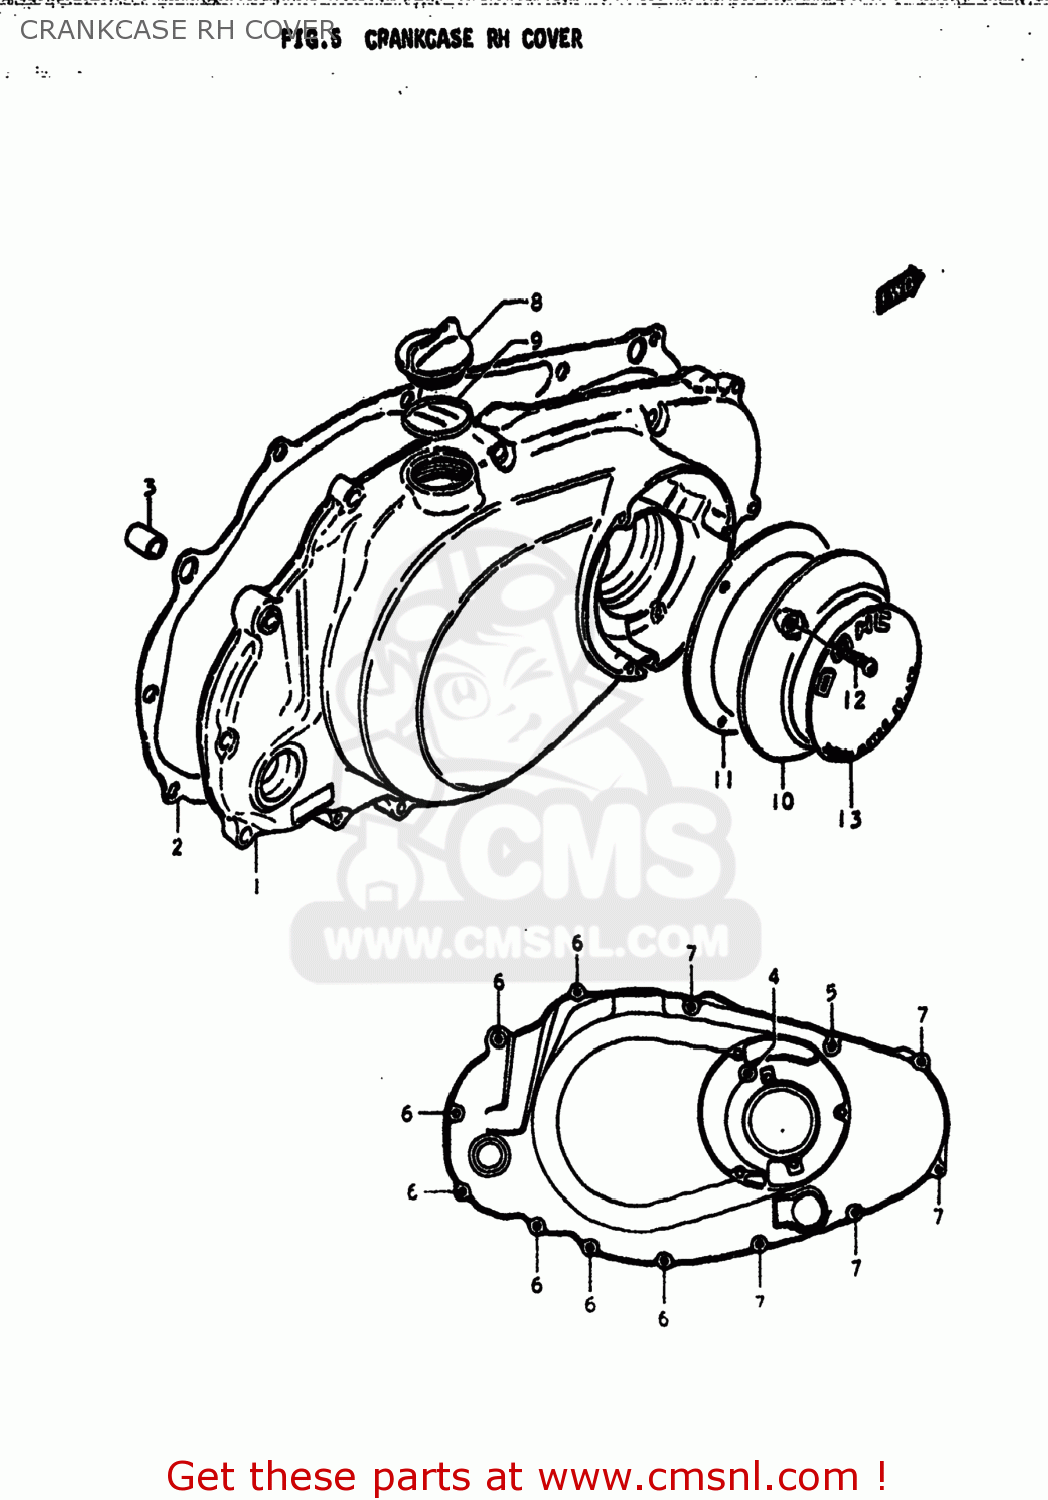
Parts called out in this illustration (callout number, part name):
1	COVER,CLUTCH
2	GASKET,CLUTCH COVER (MCA)
3	PIN
4	SCREW 6X60
5	SCREW (6X45)
6	SCREW (6X35)
7	SCREW
8	CAP
9	O RING(D:2.2,ID:32)
10	COVER,CONTACT BREAKER
11	GASKET,CONTACT BREAKER (MCA)
12	SCREW 5X20
13	EMBLEM
